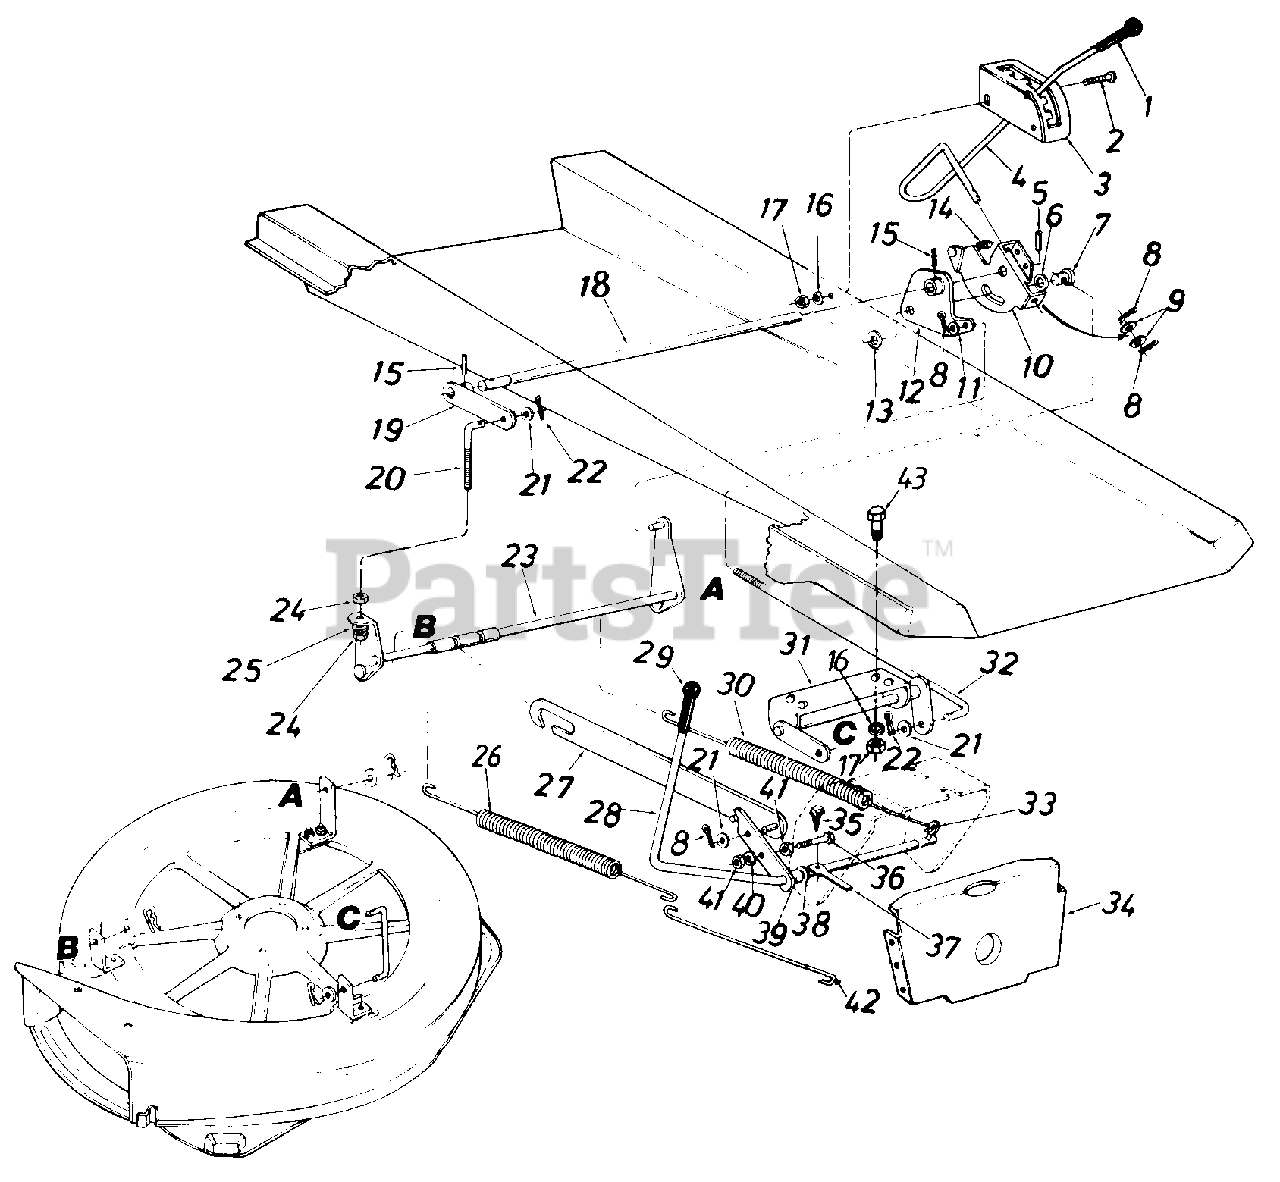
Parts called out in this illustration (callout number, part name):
2	Truss Mach. Scr. 5/16-18 x .75" Lg.
5	Spring Pin Spir. 3/16" Dia. x 1.50" Lg.
6	Fl-Wash. .385" I.D. x .87" O.D.
7	Adj. Ferrule Deck Lift Handle
8	Cotter Pin 118" Dia. x 1.00" Lg.
9	Fl-Wash. .531" I.D. x .930" O.D.
10	Deck Lift Handle Retainer Ass'y.
11	Fl-Wash. .385" I.D. x .87" O.D.
12	Deck Lift Brkt. Ass'y.-L.H.
13	Fl-Wash. .635" I.D. x 1.04" O.D.
14	Compression Spring .50" Dia. x 1.0" Lg.
15	Spring Pin Spir. 1/4" Dia. x 1.50" Lg.
16	L-Wash. 5116" I.D.
17	Hex Nut 5/16-18 Thd.
18	Rear Hgt. Adj. Shaft
19	Deck Lift Brkt. Ass'y.-R.H.
20	Deck Adj. Scr. 3/8-16 Thd.
21	Fl-Wash. .385" I.D. x .87" O.D.
22	Intern. Cotter Pin 1/2" Dia.
23	Deck Link Ass'y.-Rear
24	Hex Nut 3/8-16 Thd.*
25	L-Wash. 3/8" I.D.
26	Extension Spring .73" O.D. x 1 3.84" Lg.
30	Extension Spring .73" O.D. x 1 3.84" Lg.
31	Deck Lift Ass'y.-Front
32	Deck Lift Connecting Rod
33	Clevis Pin Special .250" Dia.
36	Hex Bolt 5/16-18 x 1.50" Lg. (Grade 5)
37	Switch Actuator
38	Fl-Wash. .531 I.D. x .930" O.D.
39	Spacer.511" I.D. x .70" O.D. x.38" Lg.
40	L-Wash. 5/16" I.D.
41	Hex Nut 5/16-18 Thd.
43	Hex Bolt 5/16-18 x .75" Lg.
